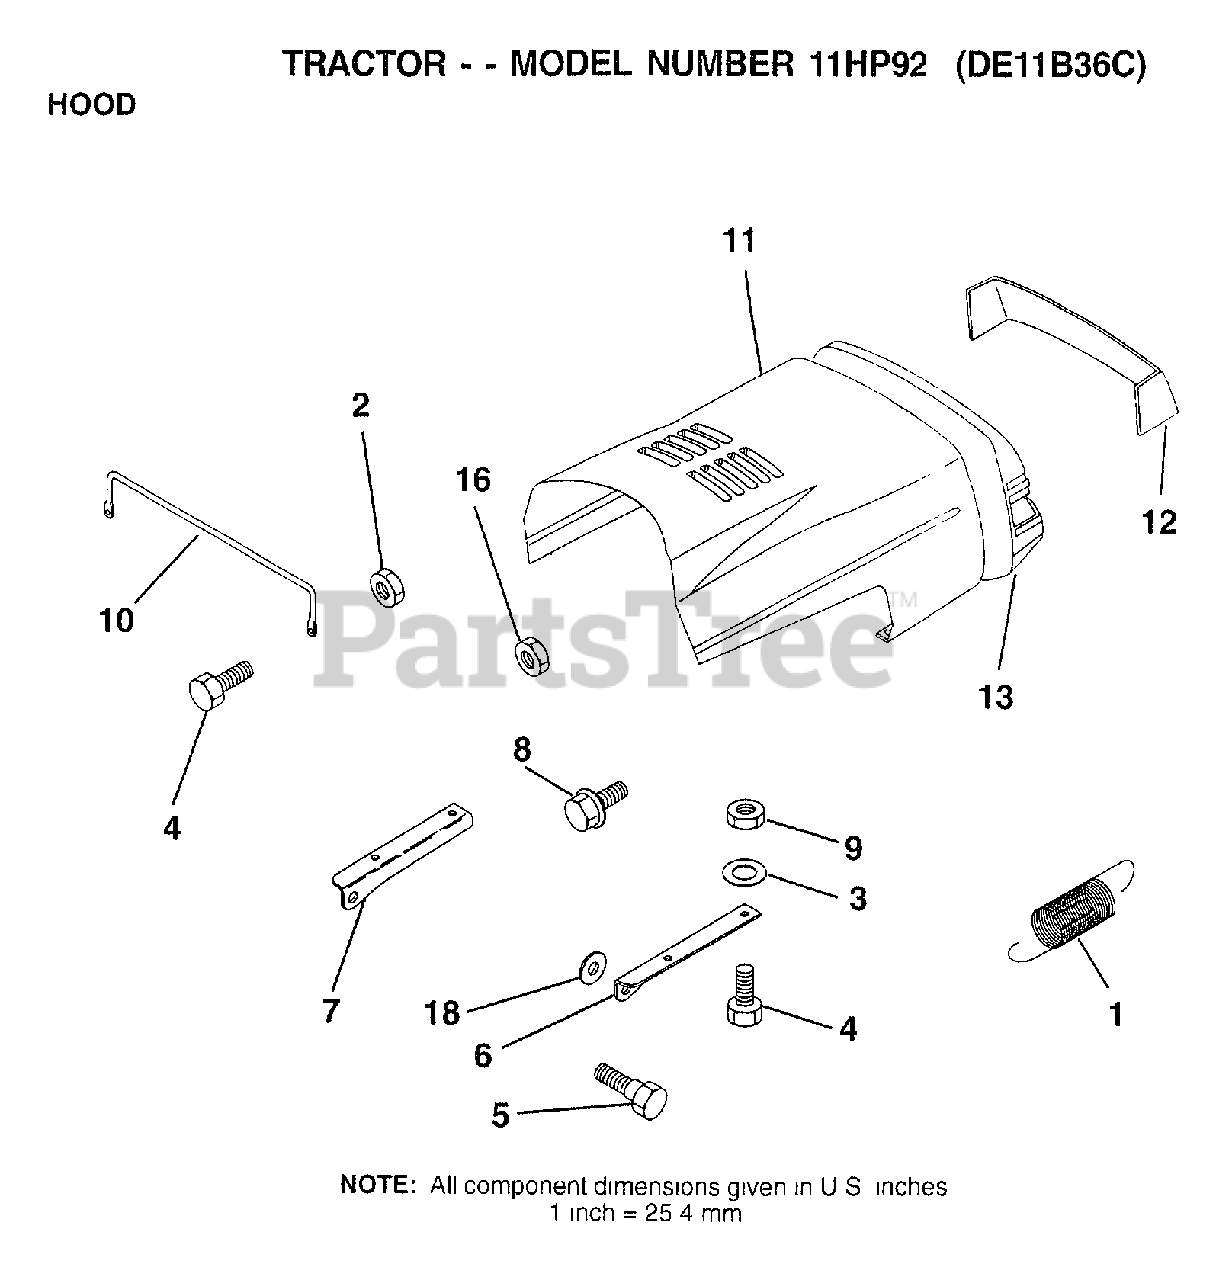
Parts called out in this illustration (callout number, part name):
1	EXT SPRING
2	NUT
3	WASHER
5	BOLT.SHLD.5/16-18
6	BRKT HOOD RH
7	BRKT HOOD LH
8	"SCREW,HWHD.HI-LO#13-16X3/4"
9	NUT
10	"BRACE,HOOD"
12	LENS.LR.JET.GRAY
13	GRILLE.LR.BLACK
16	NUT
18	WASHER
